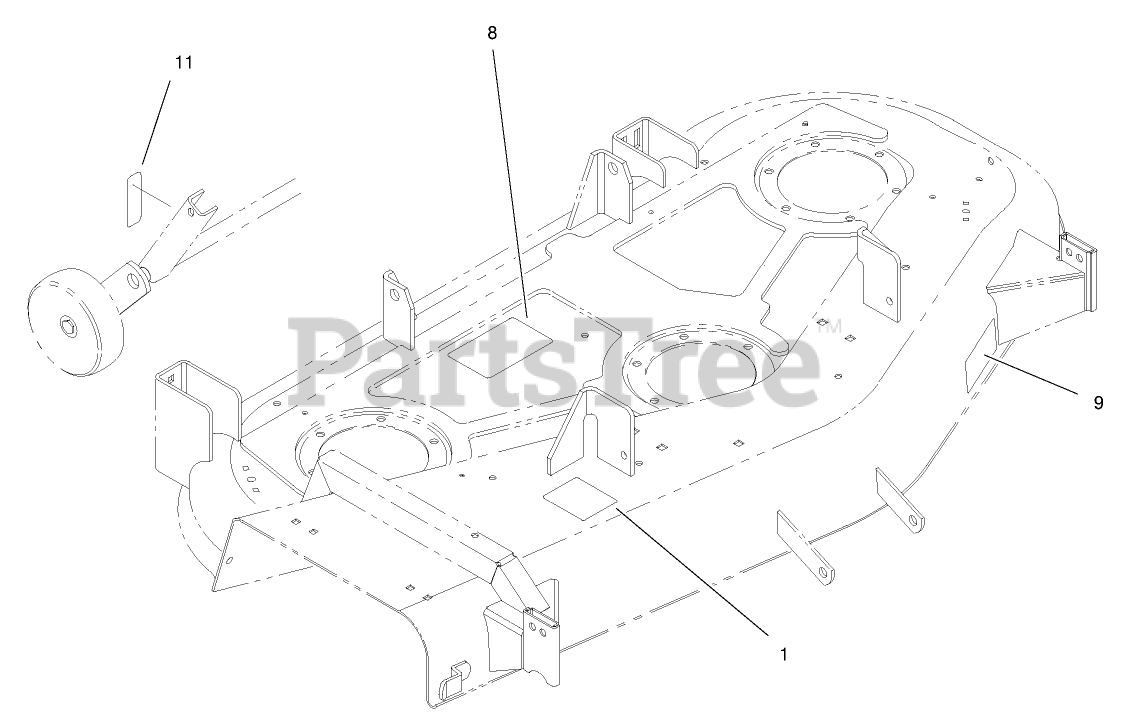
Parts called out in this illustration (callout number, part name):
1	DECAL-BELT ROUTING
8	DECAL-BELT ROUTING
9	DECAL-ADJUSTMENT, WHEEL
11	DECAL-HOC
